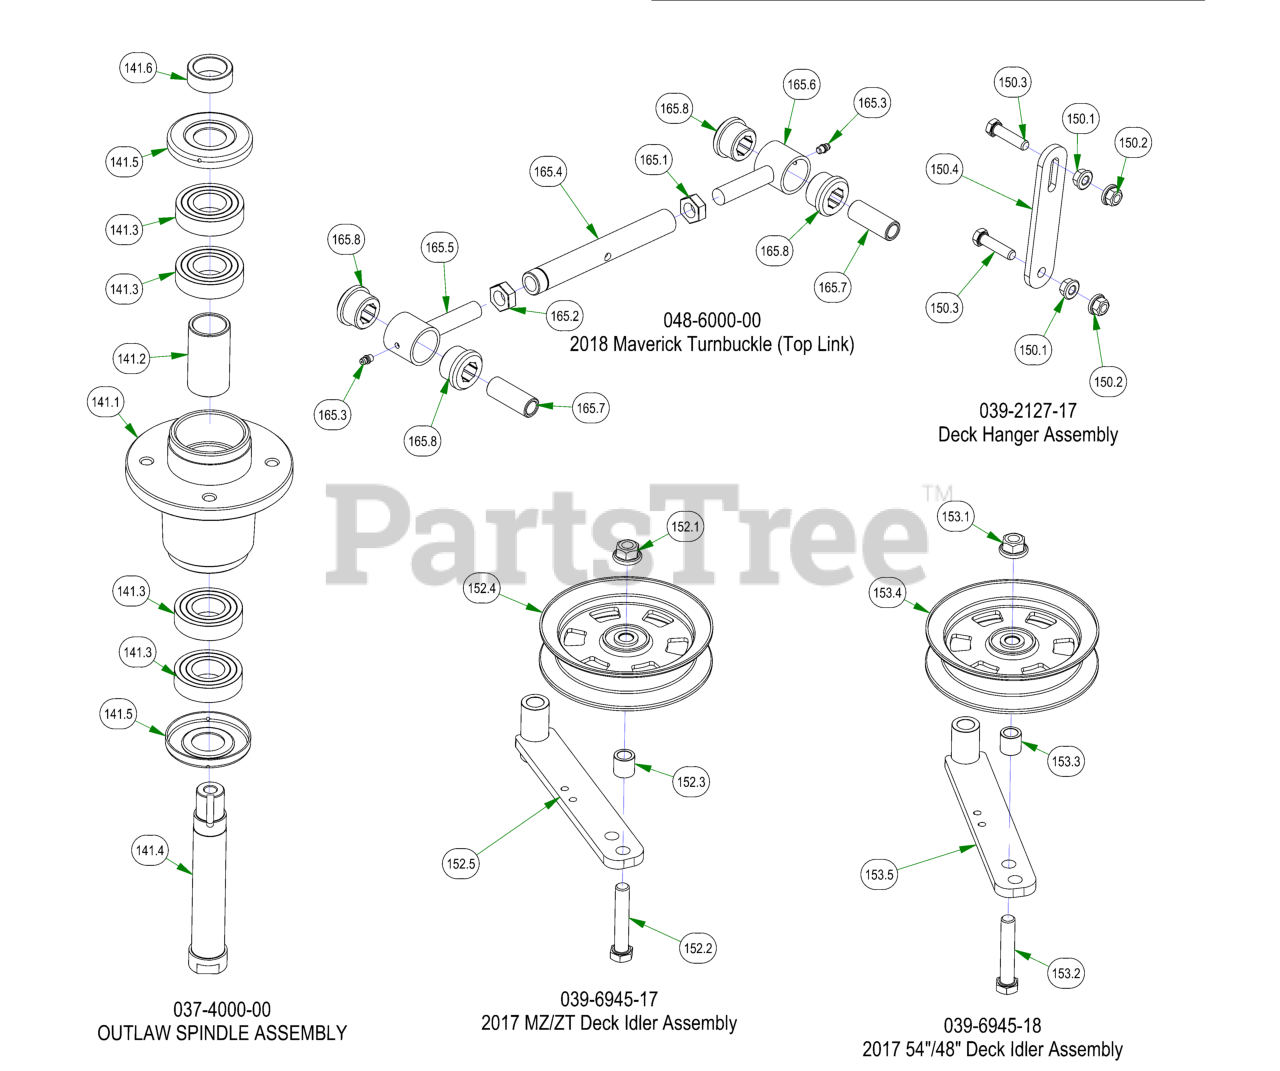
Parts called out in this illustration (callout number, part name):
141	OUTLAW SPINDLE ASSEMBLY
141.1	4000 Series Spindle Housing
141.2	4000 Series Spindle Spacer
141.3	Bearing - 6206
141.4	Spindle Shaft
141.5	Spindle Dust Cap
141.6	Locking Collar w/ 1/4"-20 Set Screw
150	Deck Hanger Assembly
150.1	3/8-16 HEX SERRATED FLANGE NUT HARD/ZINC
150.2	3/8-16 NYLON INSERT FLANGE LOCKNUT (GR.F) ZINC
150.3	3/8-16 X 1-1/2 HEX CAP SCREW (GR.5) ZINC
150.4	2017 MZ/ZT Deck Hanger
152	2017 MZ/ZT Deck Idler Assembly
152.1	1/2-13 NYLON INSERT FLANGE LOCKNUT ZINC
152.2	1/2-13 X 2-3/4 HEX CAP SCREW (GR.5) ZINC
152.3	.51 ID X .75 OD X .75 LGTH SOLID SPACER ZINC
152.4	5" Idler Pully
152.5	Deck Idler
153	2017 54"/48" Deck Idler Assembly
153.1	1/2-13 NYLON INSERT FLANGE LOCKNUT ZINC
153.2	1/2-13 X 2-3/4 HEX CAP SCREW (GR.5) ZINC
153.3	.51 ID X .75 OD X .75 LGTH SOLID SPACER ZINC
153.4	5" Idler Pully
153.5	Deck Idler
165	2018 Maverick Turnbuckle (Top Link)
165.1	NUT, 5/8-18
165.2	NUT, 5/8-18LH
165.3	1/4-28 Grease Fitting
165.4	2018 Maverick Toplink Body
165.5	2018 Maverick Bushing Retainer Left-Handed
165.6	2018 Maverick Bushing Retainer Right-Handed
165.7	2018 Maverick Bushing Sleeve
165.8	2018 Maverick Bushing
